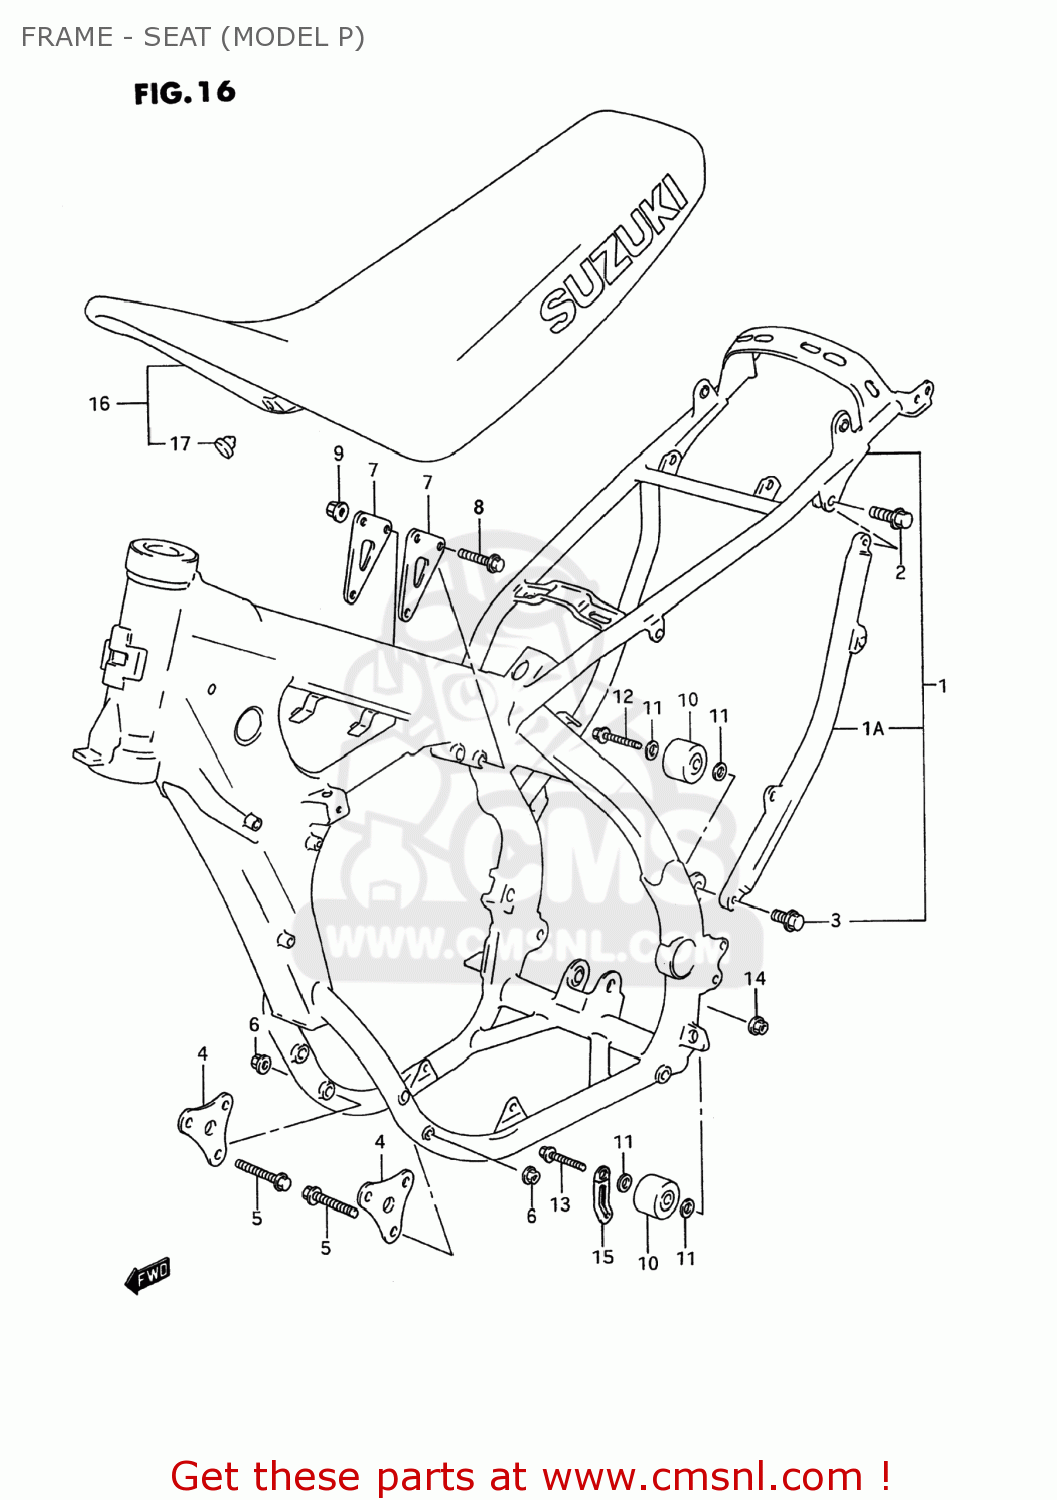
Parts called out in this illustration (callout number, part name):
1	FRAME SET
1A	TUBE,FRAME SIDE,L
2	BOLT,UPPER
3	BOLT,LOWER
4	PLATE,ENG MTG FR
5	BOLT
6	NUT
7	PLATE,ENGINE MOUNTING
8	BOLT(8X45)
9	NUT
10	ROLLER,CHAIN
11	WASHER
12	BOLT(8X41)
13	BOLT(8X45)
14	NUT
15	CLAMP
16	SEAT ASSEMBLY
17	CUSHION
